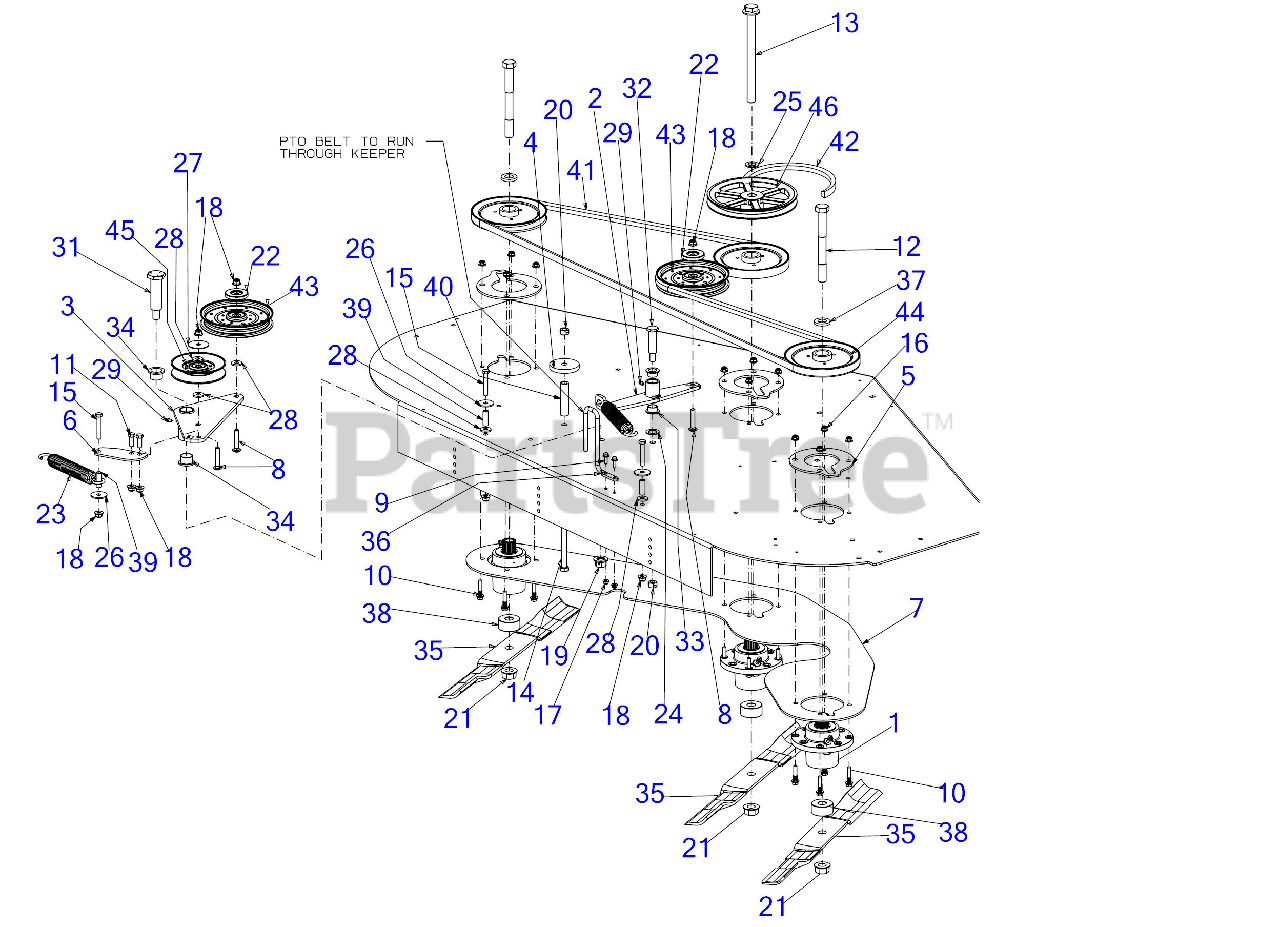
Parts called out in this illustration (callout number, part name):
1	SPINDLE ASSEMBLY
8	CARRIAGE BOLT 3/8-16 x 2
9	SCREW 1/4-20 x .75 GR5
10	BOLT 5/16-18 x 1.50 GR5
11	SCREW 3/8-16 x 1 GR5
12	SCREW 3/4-16 x 7.00 GR5
13	SCREW 3/4-16 x 9.00 GR5
14	SCREW 1/2-13 x 4.5 GR 5
15	SCREW 3/8-16 x 2.25 GR5
16	FLANGE LOCK NUT 5/16-18
17	FLANGE LOCK NUT
20	HEX NUT CTR LK 1/2-13
21	HEX FLANGE NUT 3/4
22	PULLEY CAP
23	SPRING 1.25" DIA X 8.5" LONG
24	FLAT WASHER .793ID x 1.24OD x .060
25	SHIM WASHER .76X1.25X.10
26	FLAT WASHER .406X1.500X.105
27	HUB CAP WASHER .406 x 1.92 x .060
28	FLAT WASHER .406ID X1.0 OD
29	GREASE FITTING
31	SHOULDER SCREW 1.0 x 3.15
32	SHOULDER SCREW
33	FLANGE BEARING
35	25" HI-LIFT BLADE
37	SPACER .812 ID x .218 LG
42	V-BELT B-SEC X 113.4"
43	IDLER PULLEY
44	SPINDLE PULLEY 7"
45	IDLER PULLEY 5.06 OD
46	SPINDLE DRIVE PULLEY 8.347 DIA
